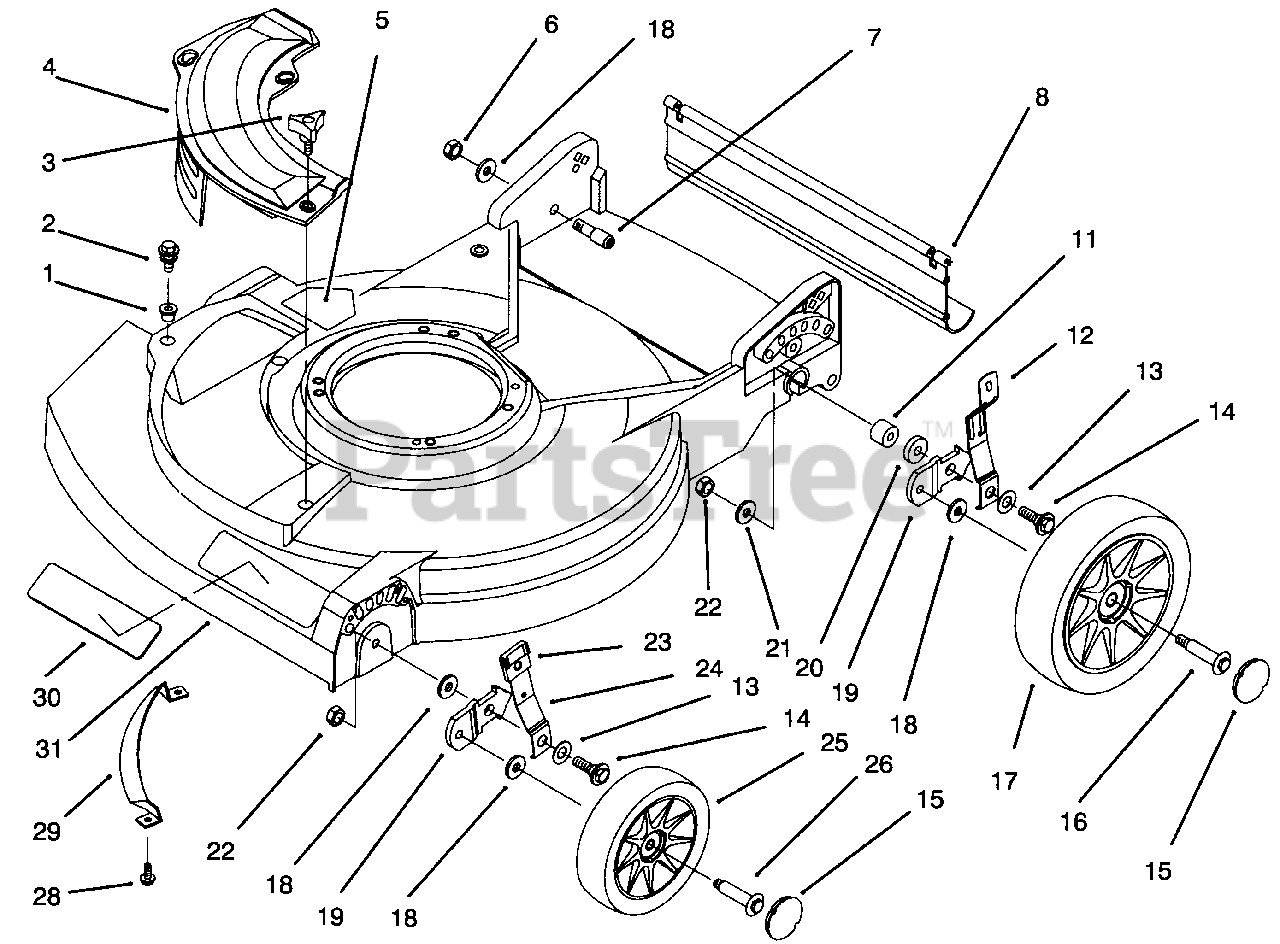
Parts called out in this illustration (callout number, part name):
1	Grommet
2	Screw-Thread Forming
3	Knob
4	Cover-Plate, Mulch
5	Decal-Danger (English)
7	Bolt-Shoulder
8	Shield-Trailing
12	Spring Arm Assembly
13	Washer-Belleville
14	Bolt-Shoulder
16	Bolt-Wheel
17	Wheel Assembly 8"
18	Washer-Wheel Bolt
19	Bracket-H. O. C.
20	Washer
22	Nut-Lock
23	Knob-Spring Arm
24	Spring Arm Assembly
25	Wheel-6"
26	Bolt-Wheel
29	Bar-Toe
30	Applique
31	Housing-21" (Incl. Ref. #5 &30)
